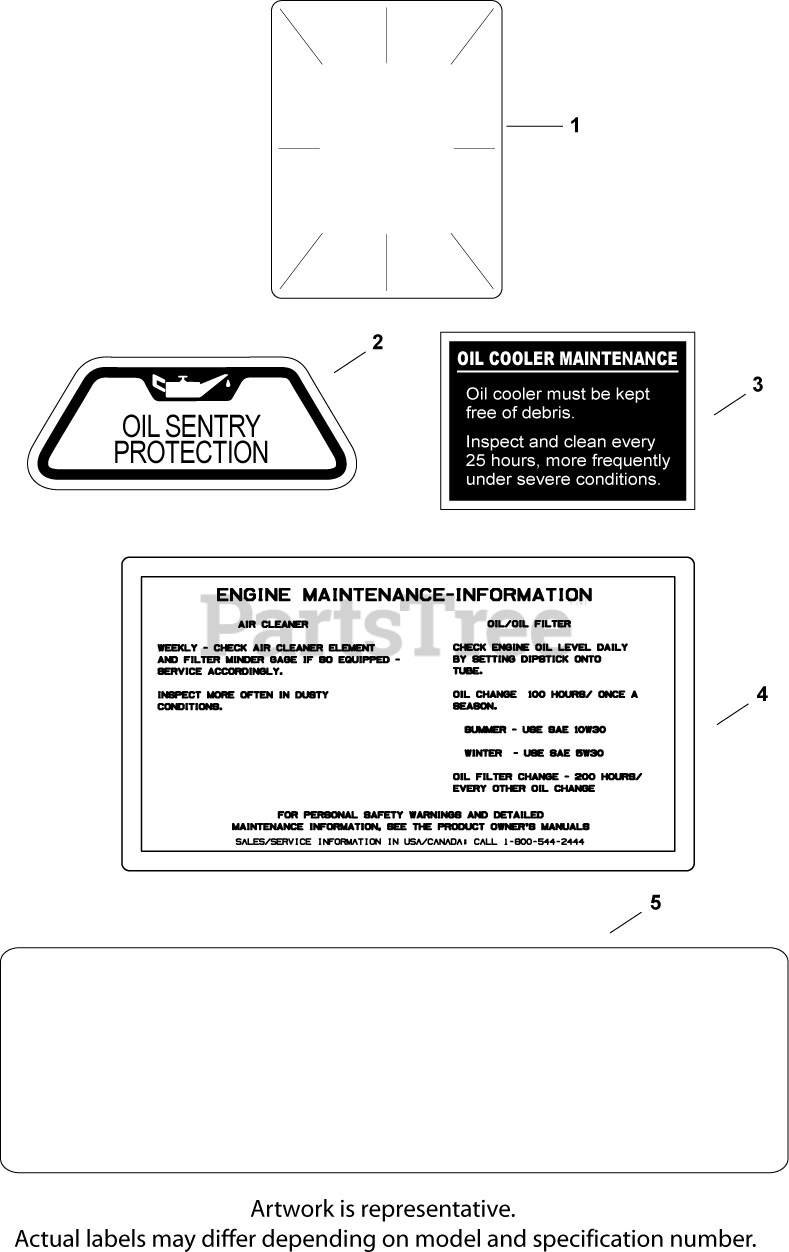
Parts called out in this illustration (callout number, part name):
1	DECAL, CLEAR LAMINATE USE 25 113 70-S
2	DECAL, OIL SENTRY - (#DSC)
3	DECAL, OIL COOLER - (#DSC)
4	DECAL, AIR CLEANER - (#DSC)
5	DECAL, 28 HP - DISCONTINUED
